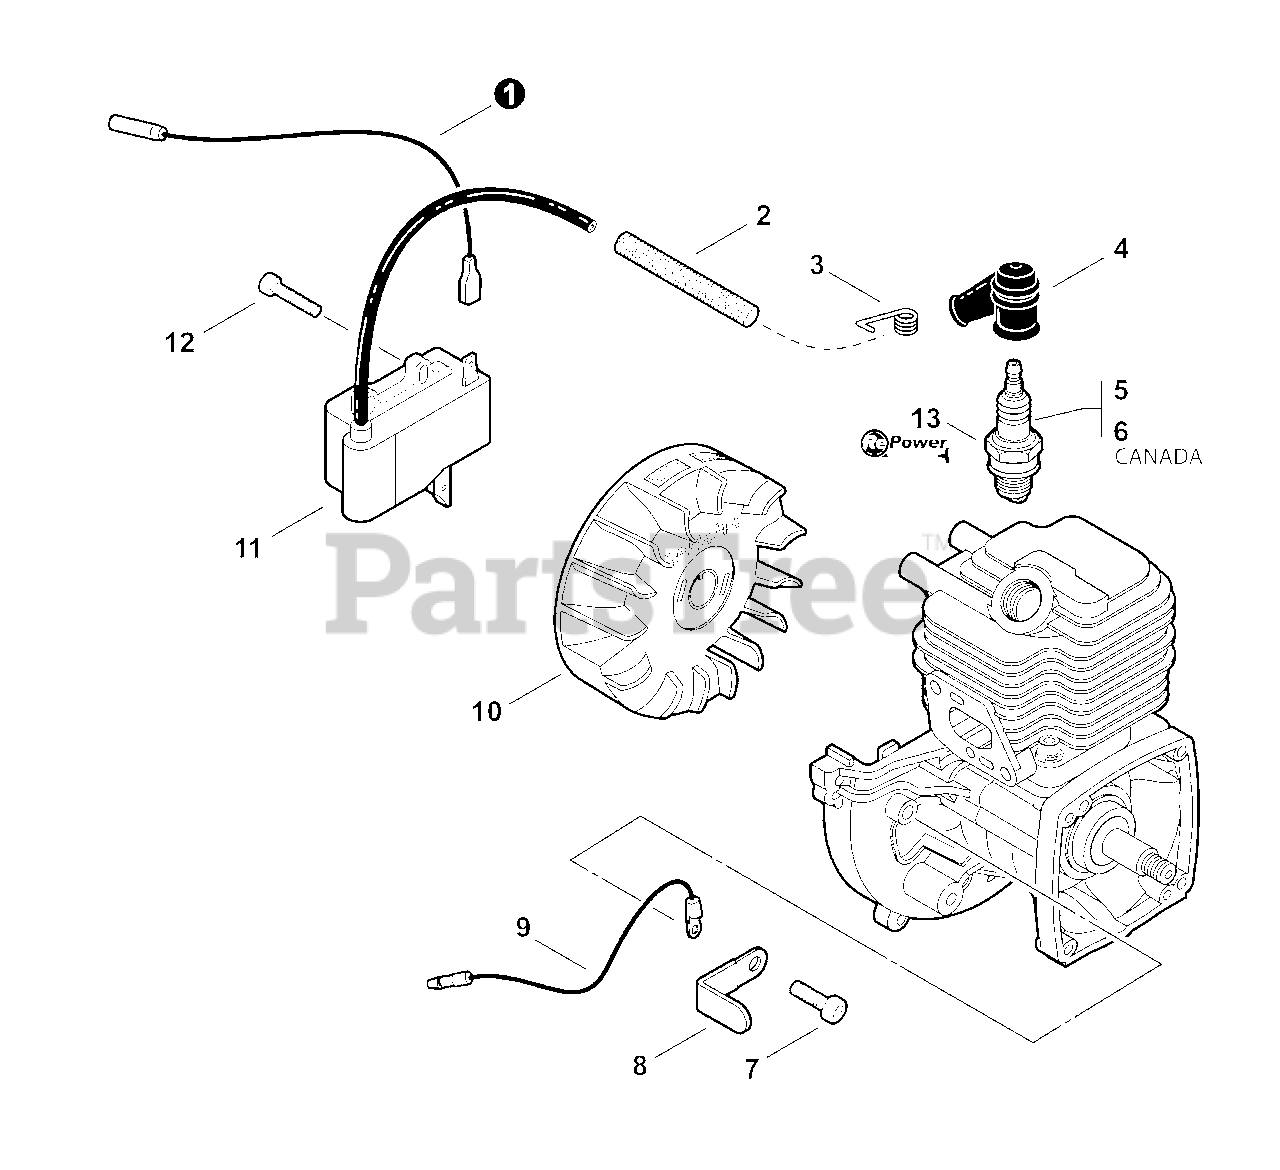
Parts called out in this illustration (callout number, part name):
1	LEAD - IGNITION
2	TUBE, INSULATOR
3	TERMINAL, SPARK PLUG CAP
4	CAP, SPARK
5	SPARK PLUG -- BPM8Y
6	SPARK PLUG -- BPMR8Y
7	SCREW - 5×10
9	LEAD - GROUND
10	FLYWHEEL
11	COIL, IGNITION
12	SCREW - 4×20 -- TORX
13	RePower TUNE UP KIT
